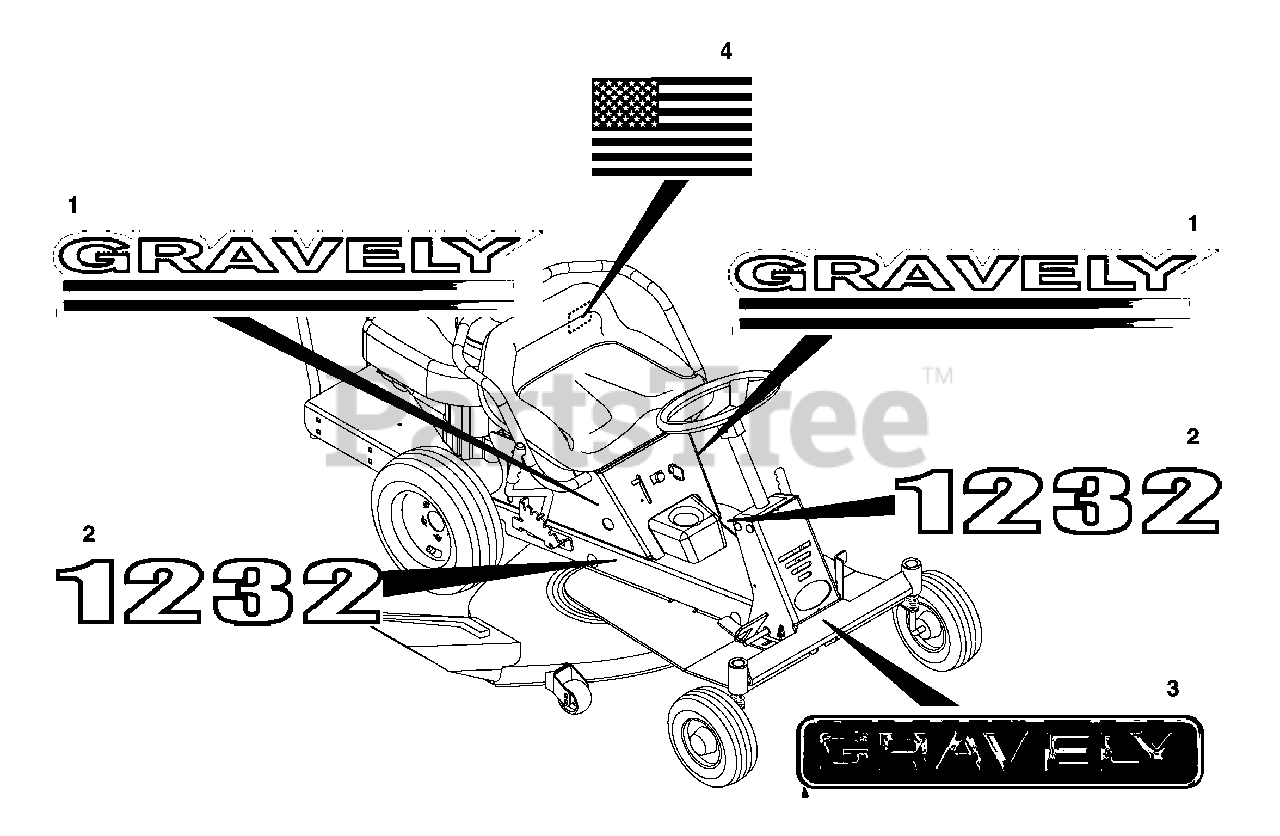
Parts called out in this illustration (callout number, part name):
1	Decal, Gravely ZT
2	Decal, Rear Engine Rider Gravely 1232 (062)
2	Decal, Rear Engine Rider Gravely 1028 (060)
2	Decal, Rear Engine Rider Gravely 1440 (064)
3	Decal, Gravely
4	Decal, American Flag
